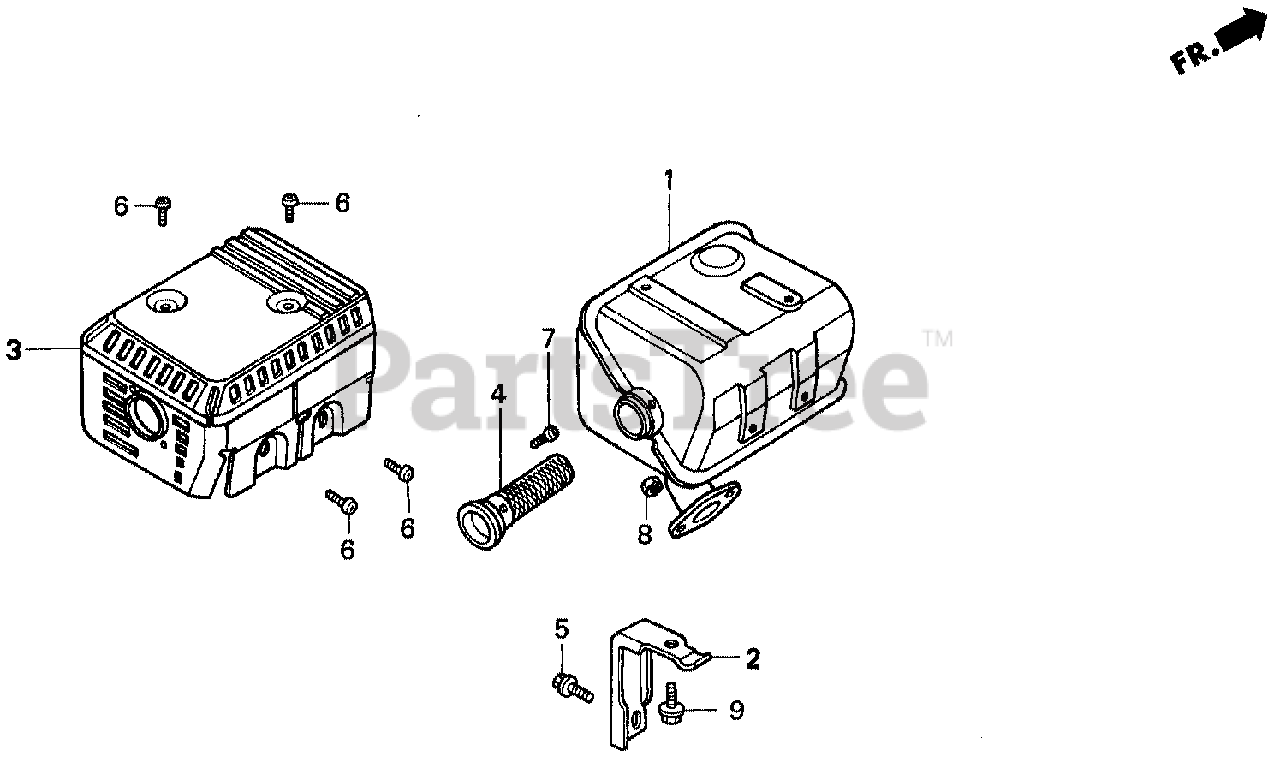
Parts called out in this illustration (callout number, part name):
1	MUFFLER (SILENT)
2	STAY, MUFFLER
3	PROTECTOR, MUFFLER
4	ARRESTER, SPARK (SILENT)
5	BOLT, FLANGE (6X13)
6	SCREW, TAPPING (5X8)
7	SCREW, TAPPING (4X6)
8	NUT, HEX. (8MM)
9	BOLT, FLANGE (6X12)
